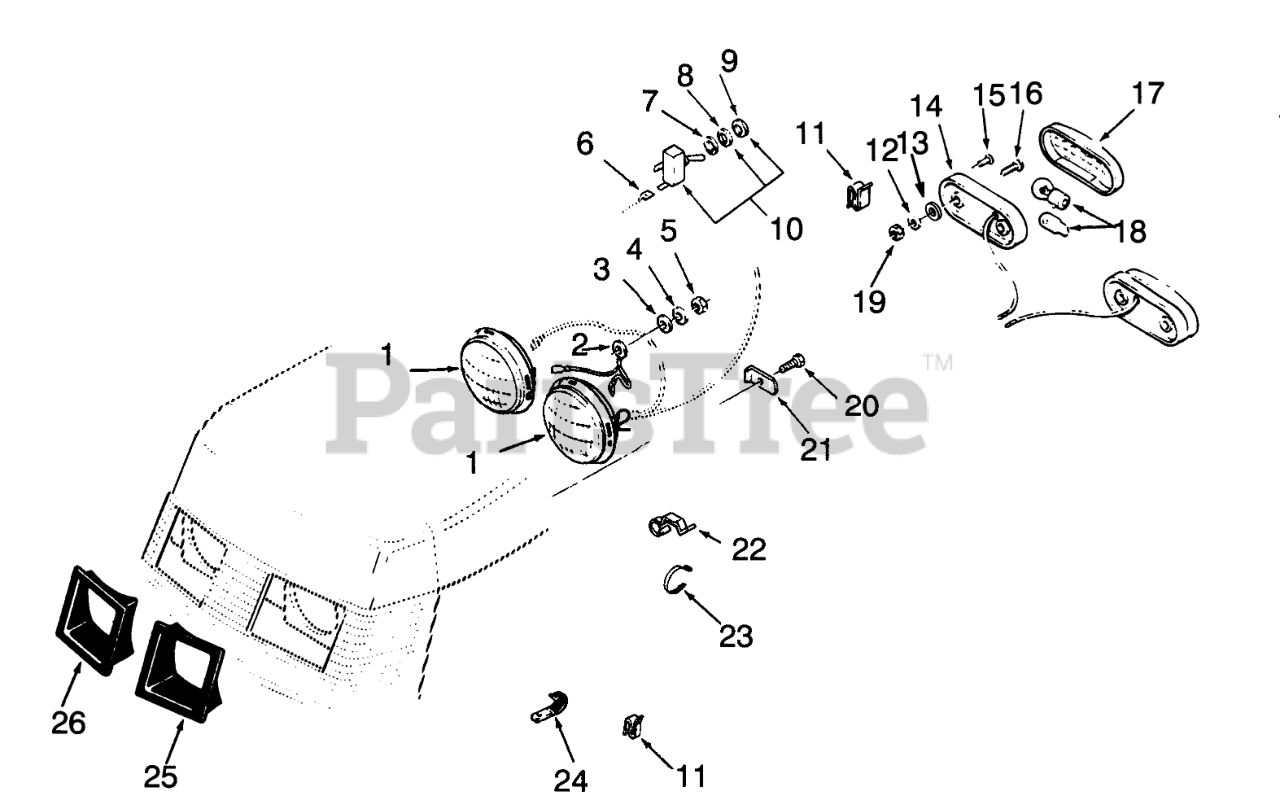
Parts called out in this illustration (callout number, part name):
1	HEADLAMP
2	LIGHT GROUND WIRE
3	WASHER-PLAIN
4	WASHER-LOCK, INTERNAL
5	NUT-LOCK, NI
6	Terminal
7	Washer
8	TAB-WASHER
10	SWITCH-LIGHTS
11	SPEED CLIP
12	WASHER-FLAT
13	WASHER-LOCK, INT
14	BASE-TAIL LIGHT
15	RIVET-POP
16	Screw
17	LENS-TAIL LIGHT
18	Bulb
19	Nut
20	Bolt
21	LOCK-HEADLIGHT
22	CLIP-WIRE
23	PLASTIC TIE
24	CLIP
25	BEZEL-HEADLIGHT, LH
26	BEZEL-HEADLIGHT, RH
